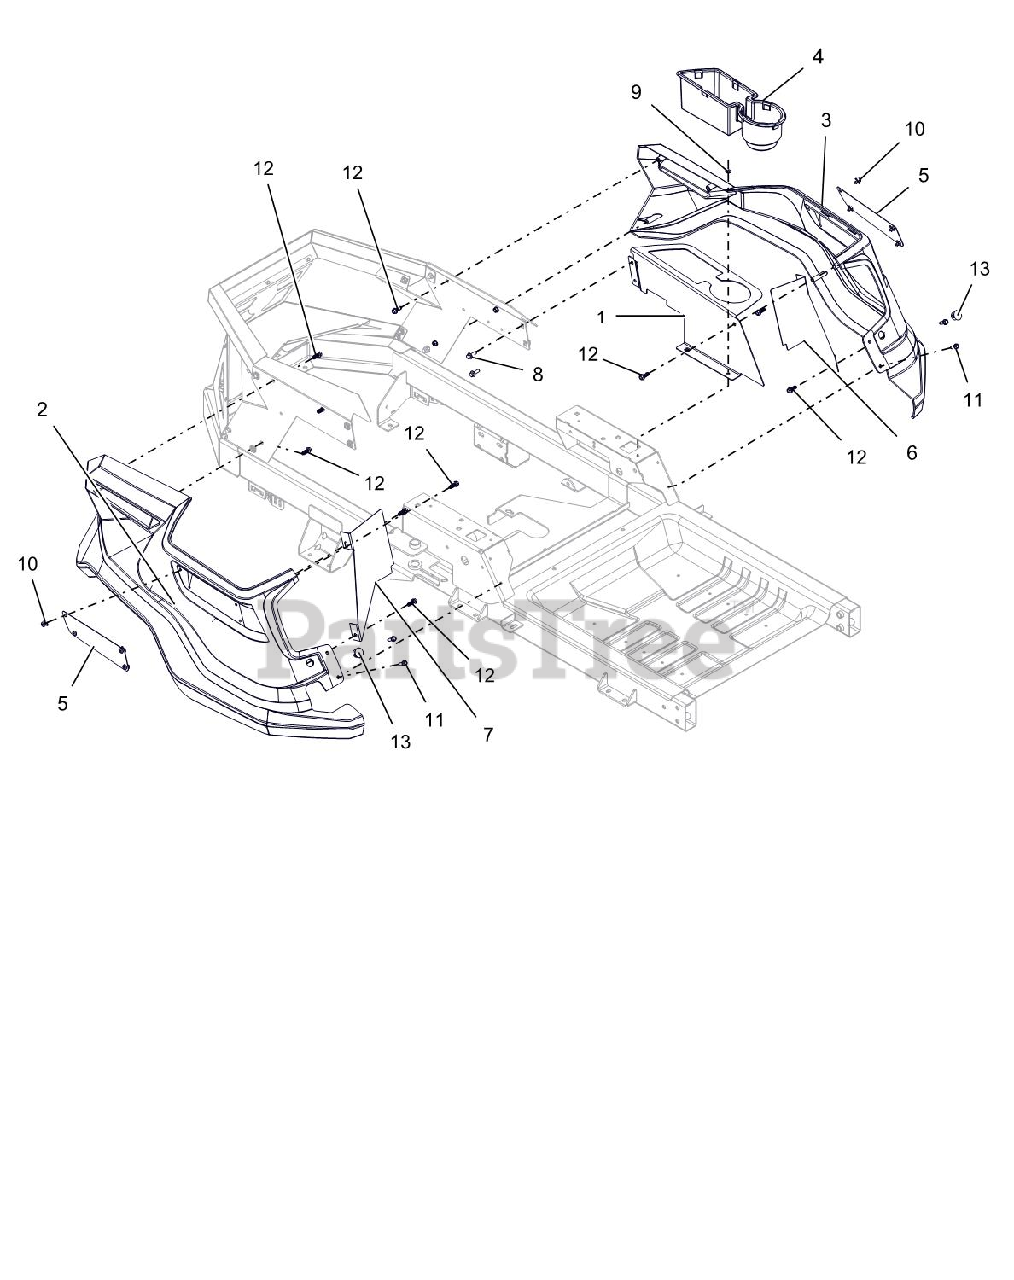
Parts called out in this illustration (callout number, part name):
1	PANEL, LEFT SIDE FENDER MOUNT
2	FENDER, RH IKON
3	FENDER, LH IKON
4	INSERT, CUP/STORAGE HOLDER
5	PLATE, ARIENS NAME
6	PLATE, LH BLOCKER
7	PLATE, RH BLOCKER
8	BLT,HEX-FLG .25-20X.75 G5 BFP
9	@WSHR-LK .25X.062 REG YWZC
10	RIVET, PLASTIC .195 DIA.
11	SCR-TAP-PM .25-20X.75 TR YWZ
12	SCR-.312X.75 #14H H/W/H H/L CZ
13	PLUG, HOLE .75 (BLACK)
